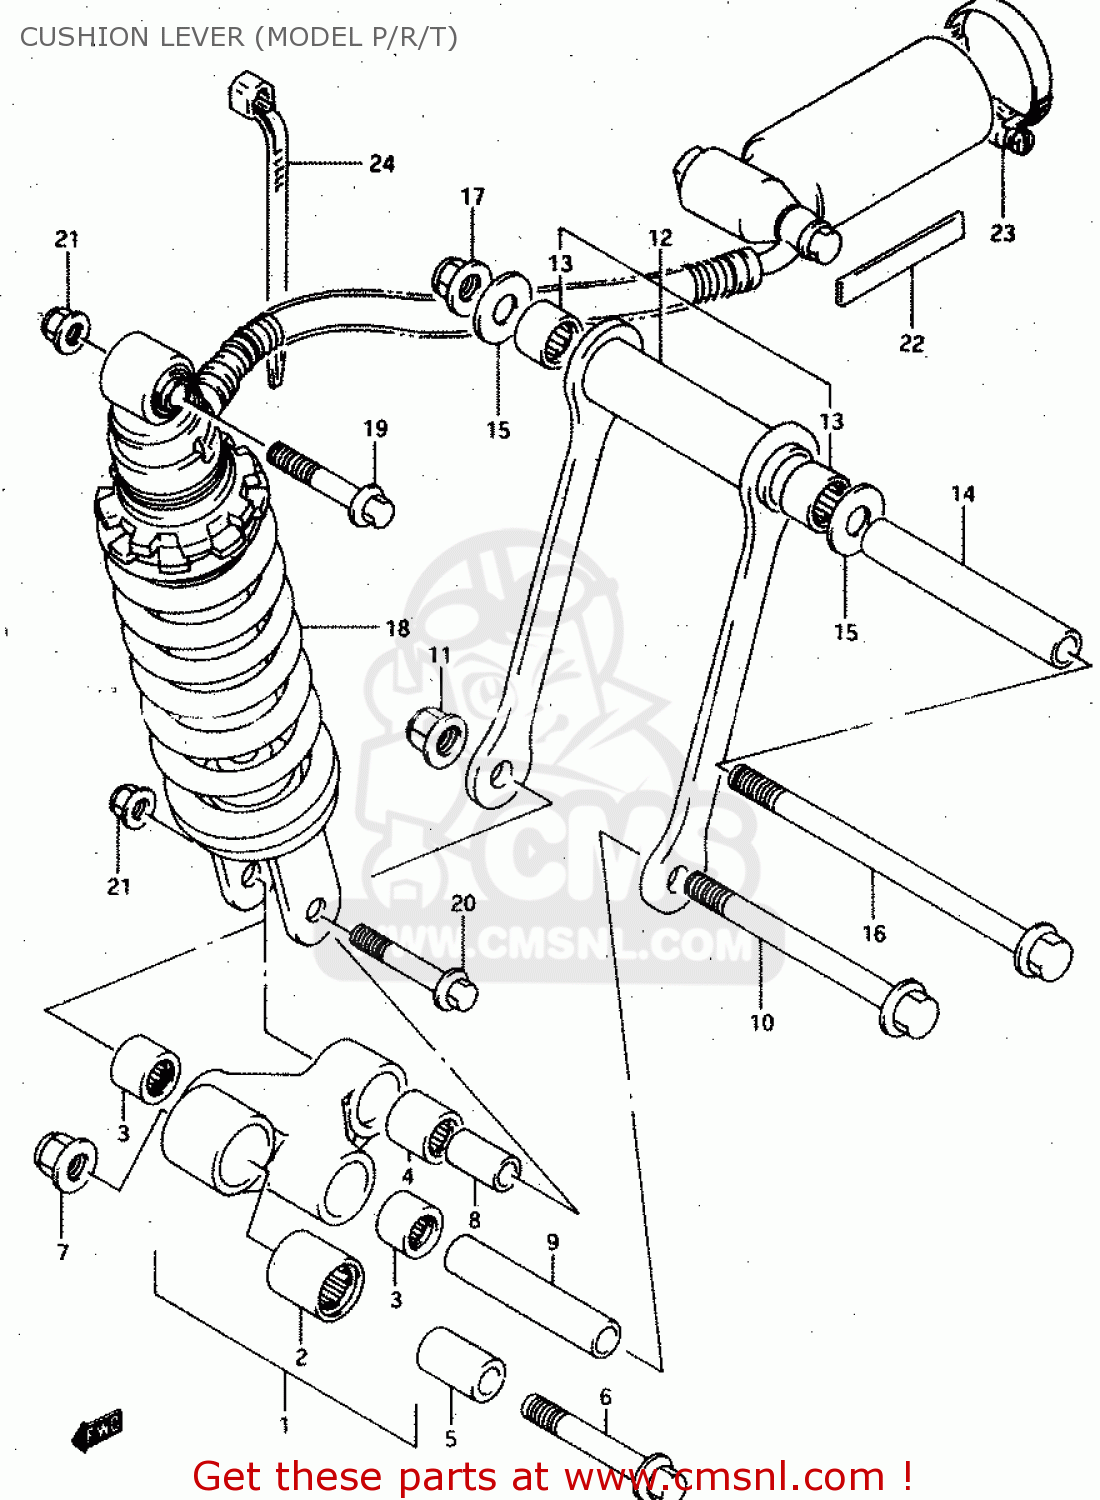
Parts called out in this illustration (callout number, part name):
1	LEVER SET,RR CUSHION
2	BEARING(20X27X30)
3	BEARING(17X24X20)
4	BEARING(17X24X26)
5	SPACER,RR CUSHION LEVER FR
6	BOLT,RR CUSHION LEVER FR
7	NUT 12MM
8	SPACER,RR CUSHION LEVER
9	SPACER(12X17X85)
10	BOLT(12X115)
11	NUT 12MM
12	ROD SET, REAR CUSHION LEVER
13	BEARING(17X24X20)
14	SPACER
15	WASHER
16	BOLT(12X155)
17	NUT 12MM
18	ABSORBER ASSY, REAR SHOCK
19	BOLT(10X75)
20	BOLT(10X54)
21	NUT
22	CUSHION,RESERVOIR TANK
23	CLAMP
24	CLAMP(L:125)
